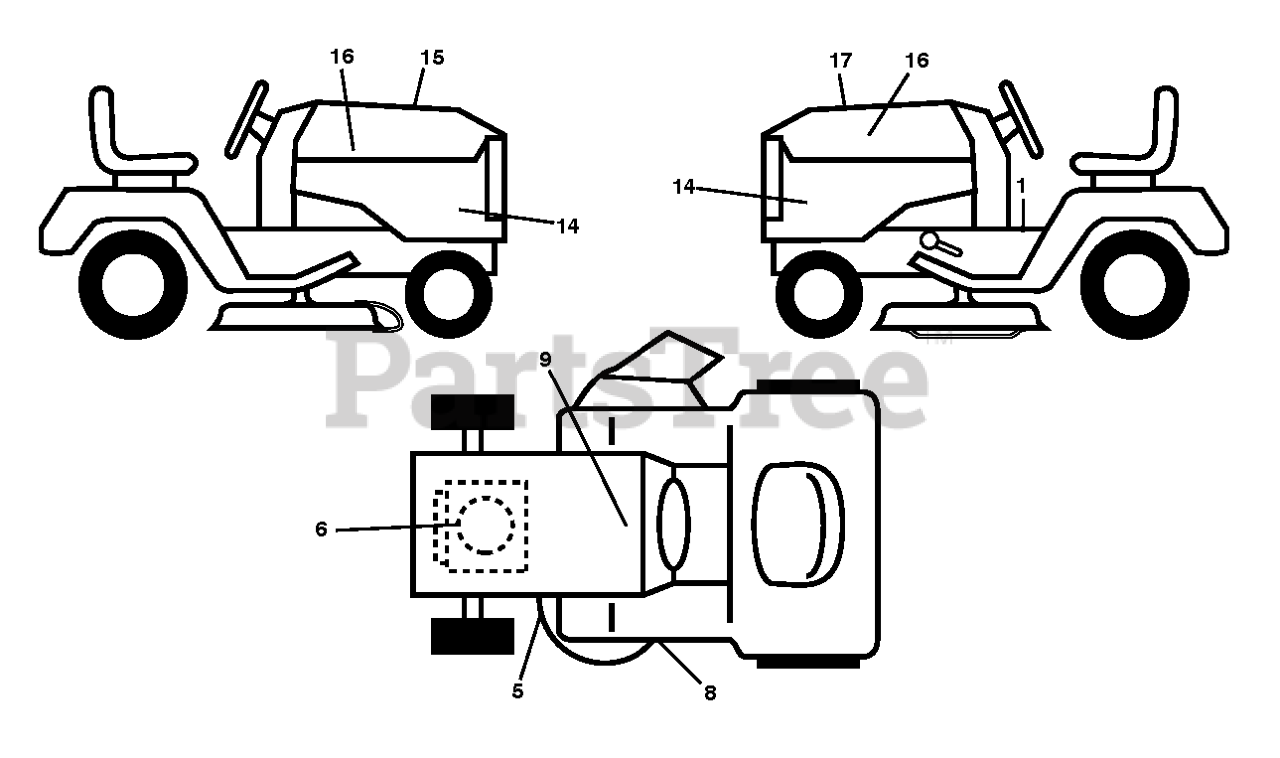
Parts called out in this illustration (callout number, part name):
1	DECAL.FENDER.WARNING
5	DECAL.MOWER
6	DECAL.ENG.BS.23HP.XRD.TWIN
8	DECAL.MOWER.SCH.48/54
9	DECAL BTRY SYMBOLS
14	DECAL.SDPNL.HUSQ.GT2.YTH23V48
15	DECAL.WARNING.CUST.RESP.E85.
16	DECAL.BADGE.170MM.TEXTLOGO.
17	DECAL.RPL.BSM44.INK.TLW.48.K46
